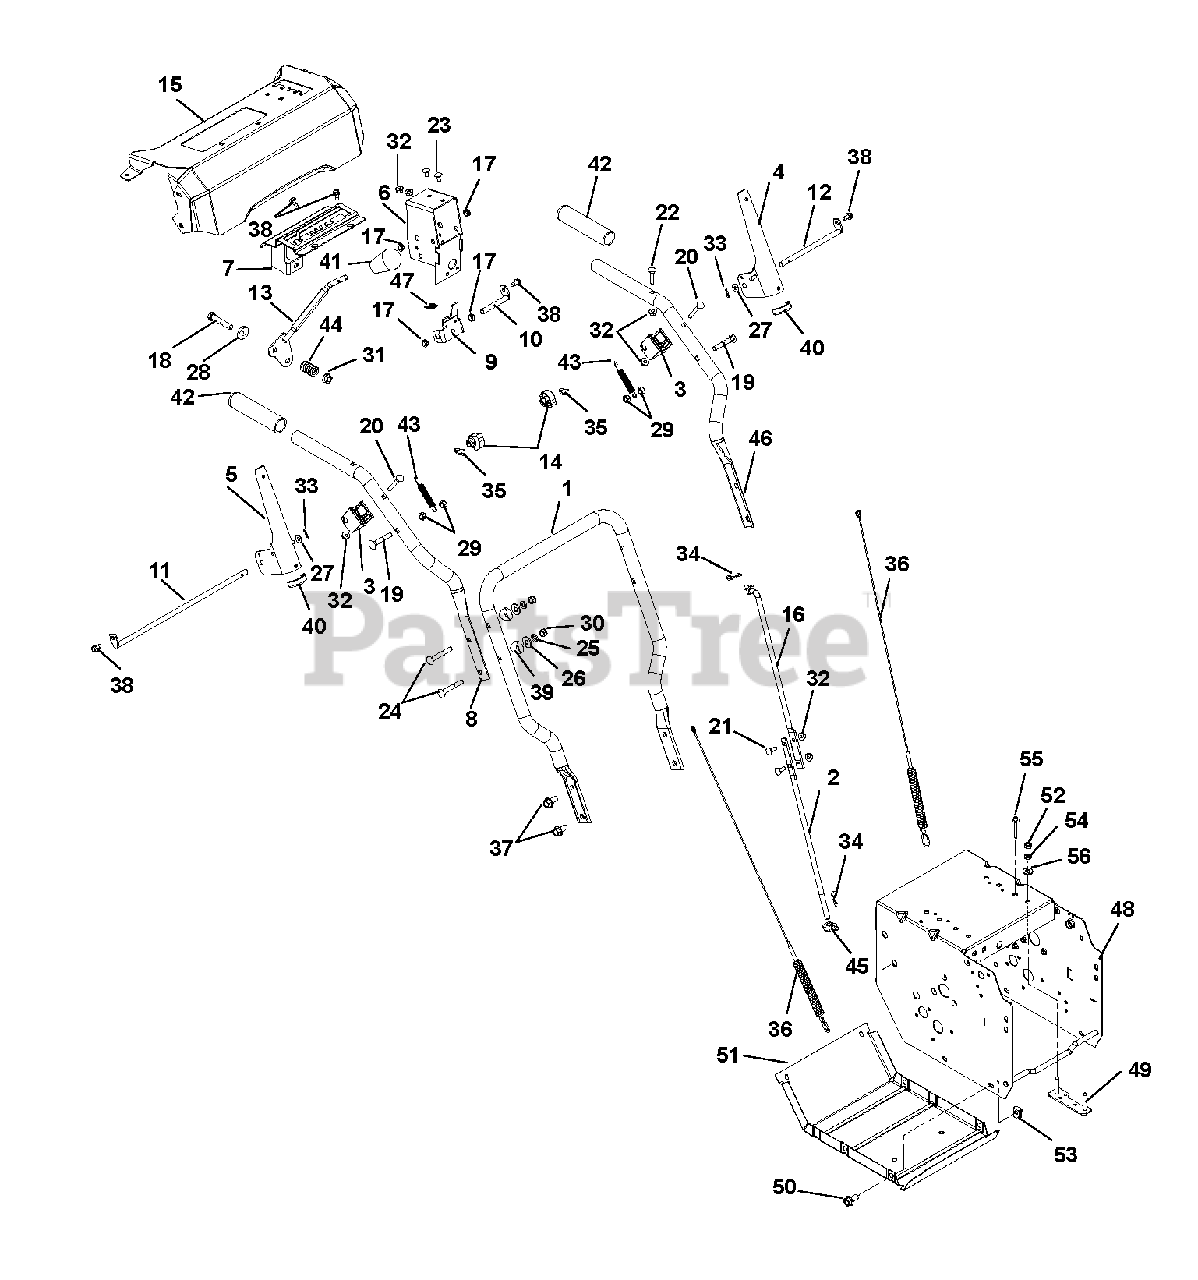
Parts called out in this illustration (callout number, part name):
1	Handlebar, Lower
2	Rod, Shift, Lower
3	Clutch Paddle Block
4	Clutch Handle, Left Hand
5	Clutch Handle, Right Hand
6	Bracket, Interlock
7	Detent Plate
8	Handlebar, Upper, Right Hand
9	Interlock Arm
10	Rod, Pivot
11	Rod, Paddle Mount, Long
12	Rod, Paddle Mount, Short
13	Lever, Shift
14	Cam, Interlock
15	Control Panel with Decal
16	Rod, Shift, Upper
17	Bushing, Polyliner
18	Bolt, Hex .38-16 x 2.00
19	Bolt, Round Head Extra Long Square Neck .31-18 x 2.00
20	Bolt, Round Head Extra Long Square Neck .25-20 x 2.00
21	Bolt, Round Head Square Neck .25-20 x .75
22	Bolt, Round Head Extra Long Square Neck .25-20 x 1.25
23	Bolt, Round Head Square Neck .25-20 x .50
24	Bolt, Round Head Square Neck .31-18 x 2.25
25	Washer, Lock .312 x .097
26	Washer, Flat Steel .38 x .875 x .083
27	Washer, Flat Steel .281 x .62 x .065
28	Washer, Flat Steel .406 x 1.00 x .188
29	Nut, Locking Center .31-18
30	Nut, Locking Nylon .31-18
31	Nut, Locking Top Flange .38-16
32	Nut, Locking Top Flange .25-20
33	Pin, Hair, Internal .06 x .18 x .77
34	Pin, Hair, Internal .08 x .18 x 1.18
35	Pin, Spring Clip
36	Cable, Control
37	Bolt, Serrated Hex Flange Washer Head .38-16 x .75
38	Screw, Tapping Hex Washer Head Thread Rolling .25-20 x .50
39	Spacer, Handlebar
40	Edging, Clutch Handle
41	Knob
42	Handle Grip
45	Pivot, Shift Rod
46	Handlebar, Upper, Left Hand
49	Strap, Engine Bolt
50	Bolt, Hex Washer Head .25-20 x .75
51	Cover, Bottom
52	Nut, Hex .31-18
53	Nut, Retainer .25-20 x .56
54	Washer, Lock .31 x .097
55	Rivet, Pop .187
56	Washer, Flat Steel .344 x .688 x .065
